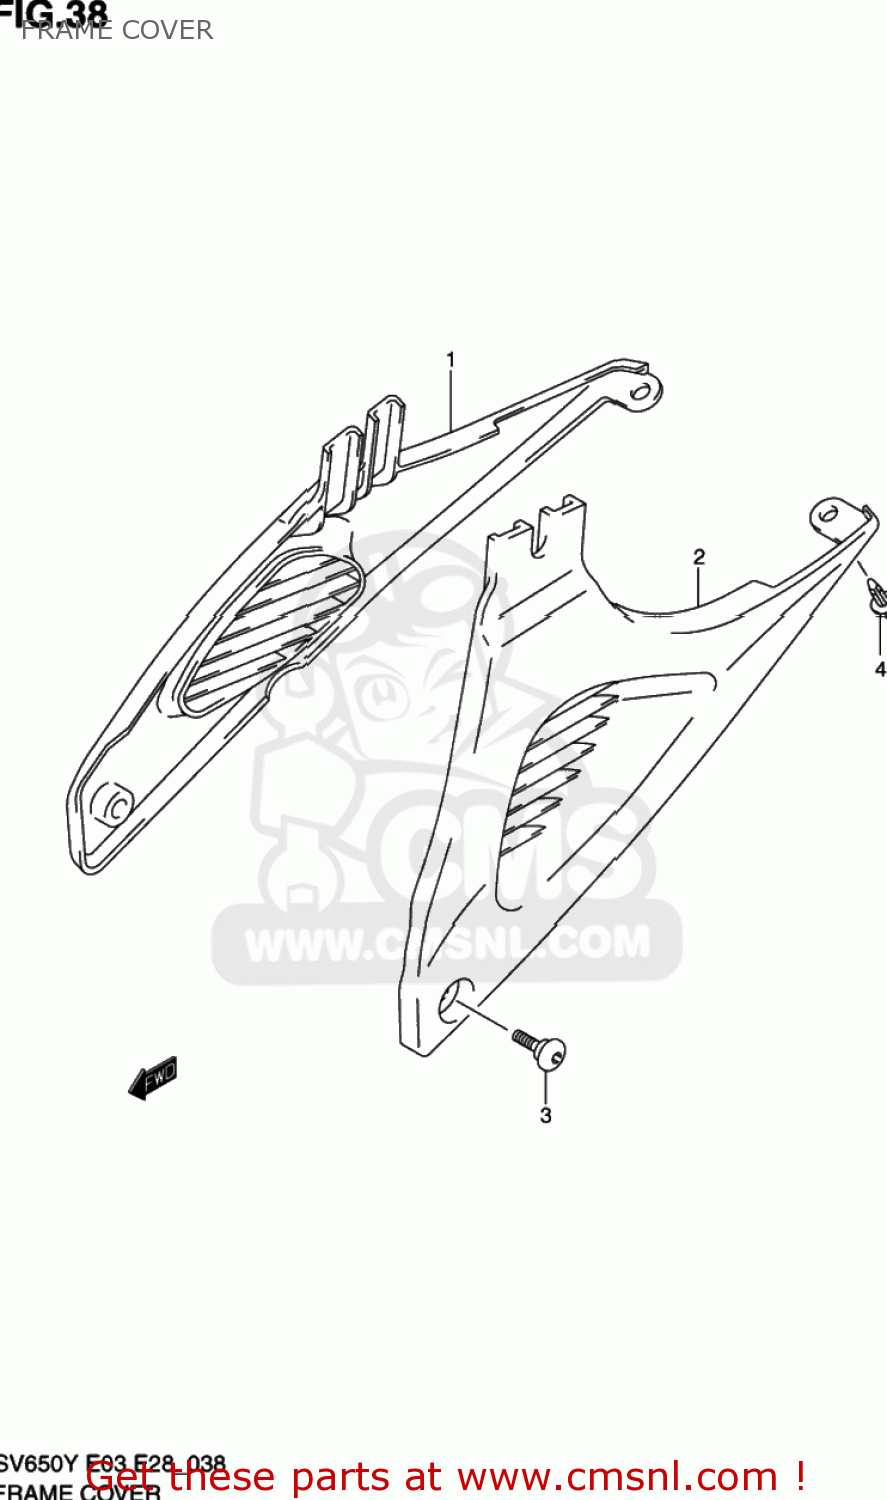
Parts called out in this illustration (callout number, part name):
1	COVER,FRAME,R
2	COVER,FRAME,L
3	SCREW(5X16)
4	CLIP(BLACK)
